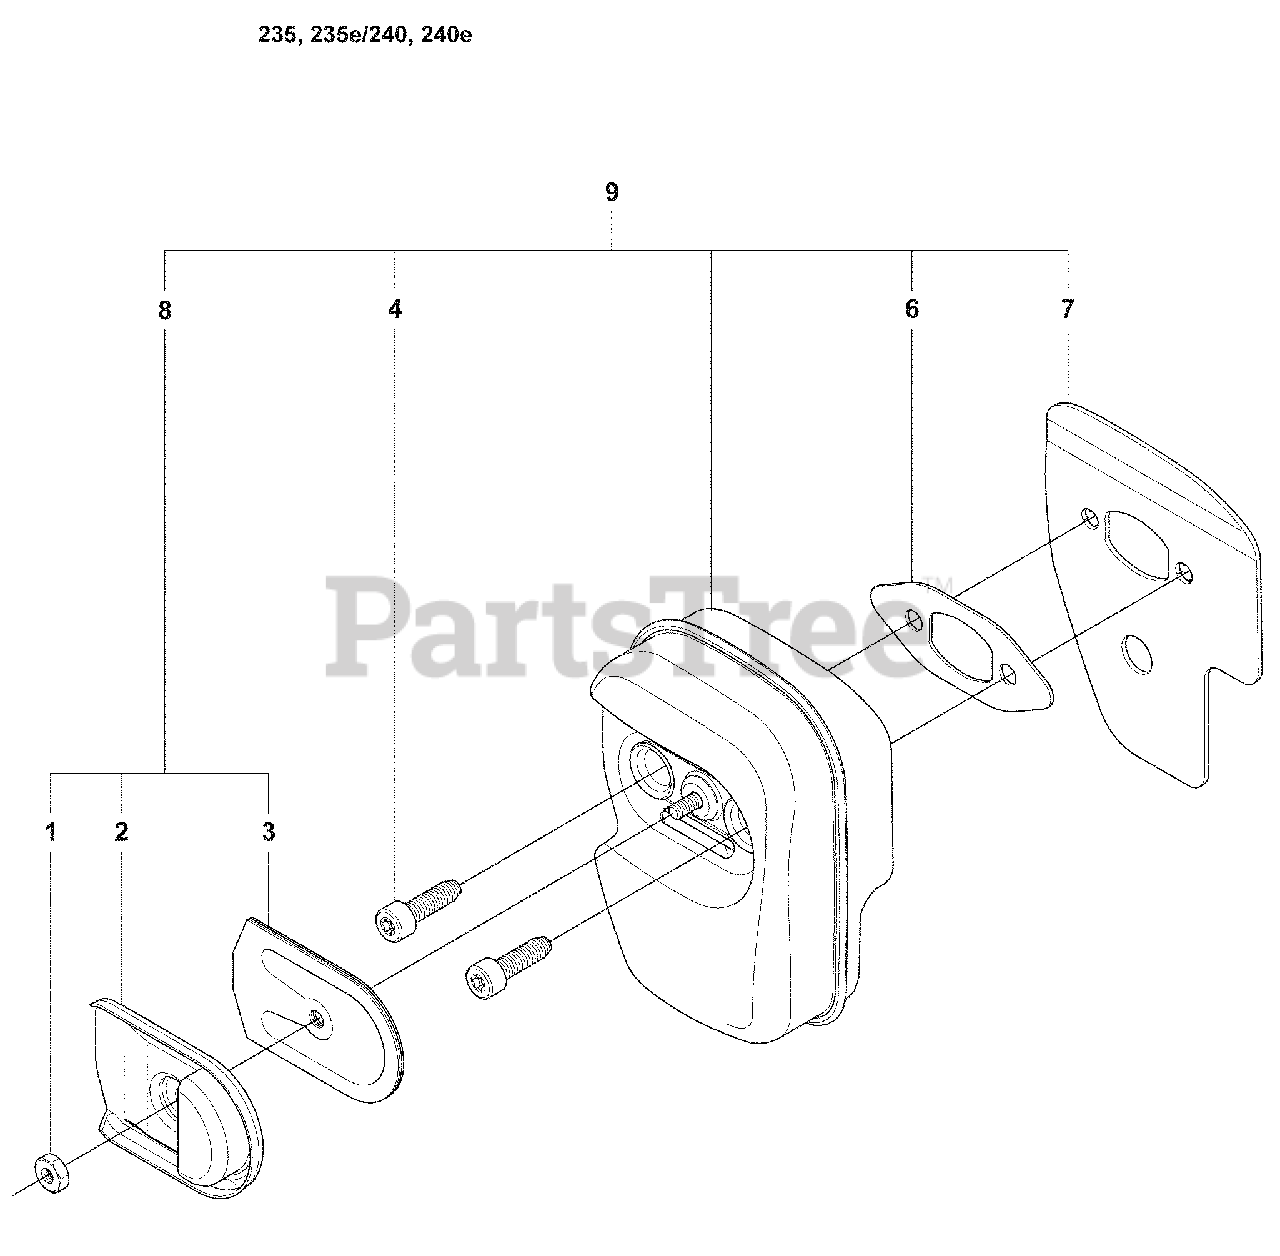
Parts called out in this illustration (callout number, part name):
1	NUT, #10-24 BRASS
2	exhaust plate
3	SCREEN-ARRESTOR, Gasket
4	muffler bolt
6	muffler gasket
7	muffler back plate
8	Kit spark arrestor
9	Kit Muffler complete
